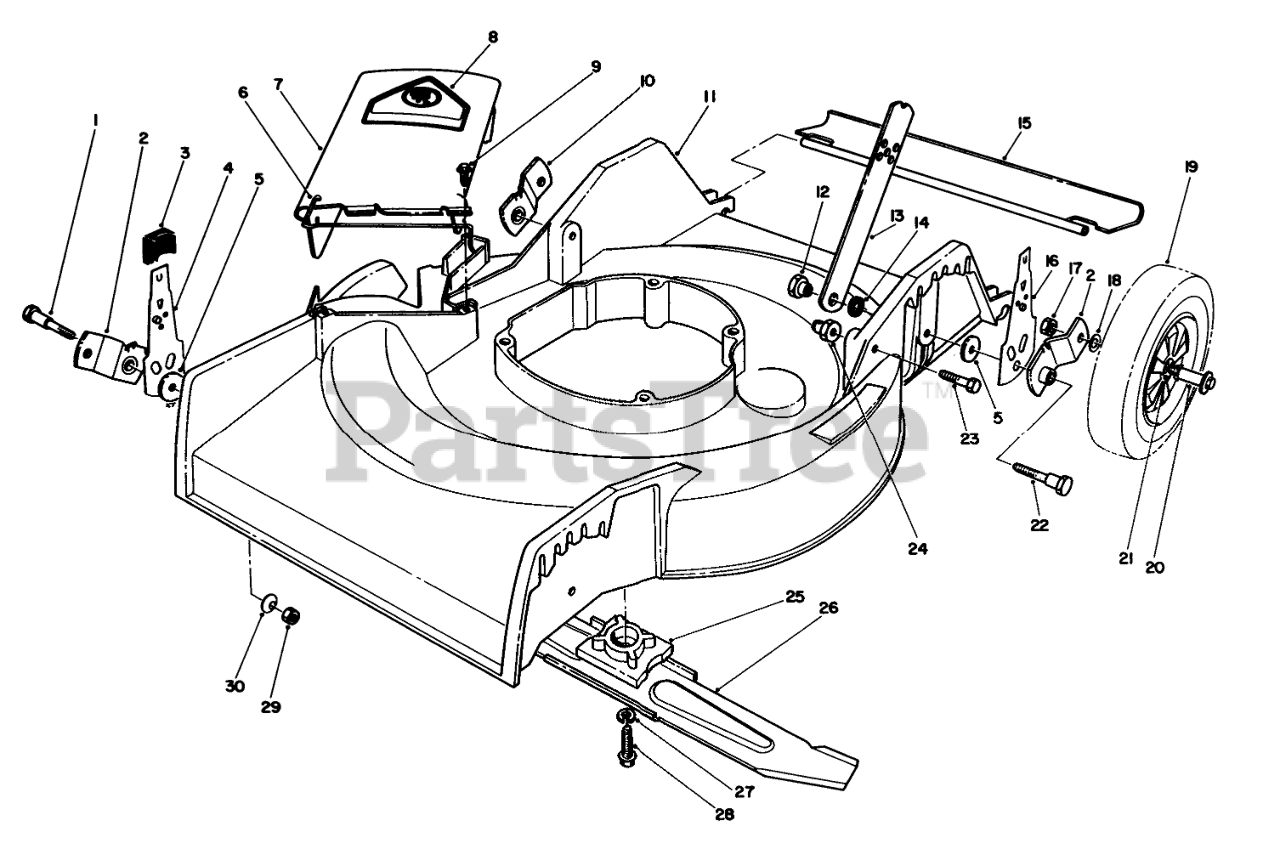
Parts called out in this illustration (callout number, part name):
1	5/16-18 PIVOT SCREW
2	Pivot Arm
3	KNOB-ARM
4	RH FRONT SPRING ARM ASM
5	PIVOT WASHER
6	SPRING HINGE
7	Deflector Assembly (Incl. Ref. #6 & 8)
8	DECAL-DANGER
9	SCREW-HWH
10	Pivot Arm
11	Housing
12	HANDLE PIVOT NUT
13	HANDLE LATCH
14	SPACER
15	SHIELD - TRAILING
16	REAR SPRING ARM ASM
17	Nut
18	WASHER
19	Wheel & Tire Assembly (Incl. Ref. #21)
20	BOLT-WHEEL
21	BUSHING
22	PIVOT SCREW
23	SCREW-HH
24	HANDLE PIVOT NUT
25	BLADE RETAINER
26	Blade
27	WASHER-LOCK
28	SCREW-HH
29	NUT-LOCK, NI
30	WASHER-BELLEVILLE
